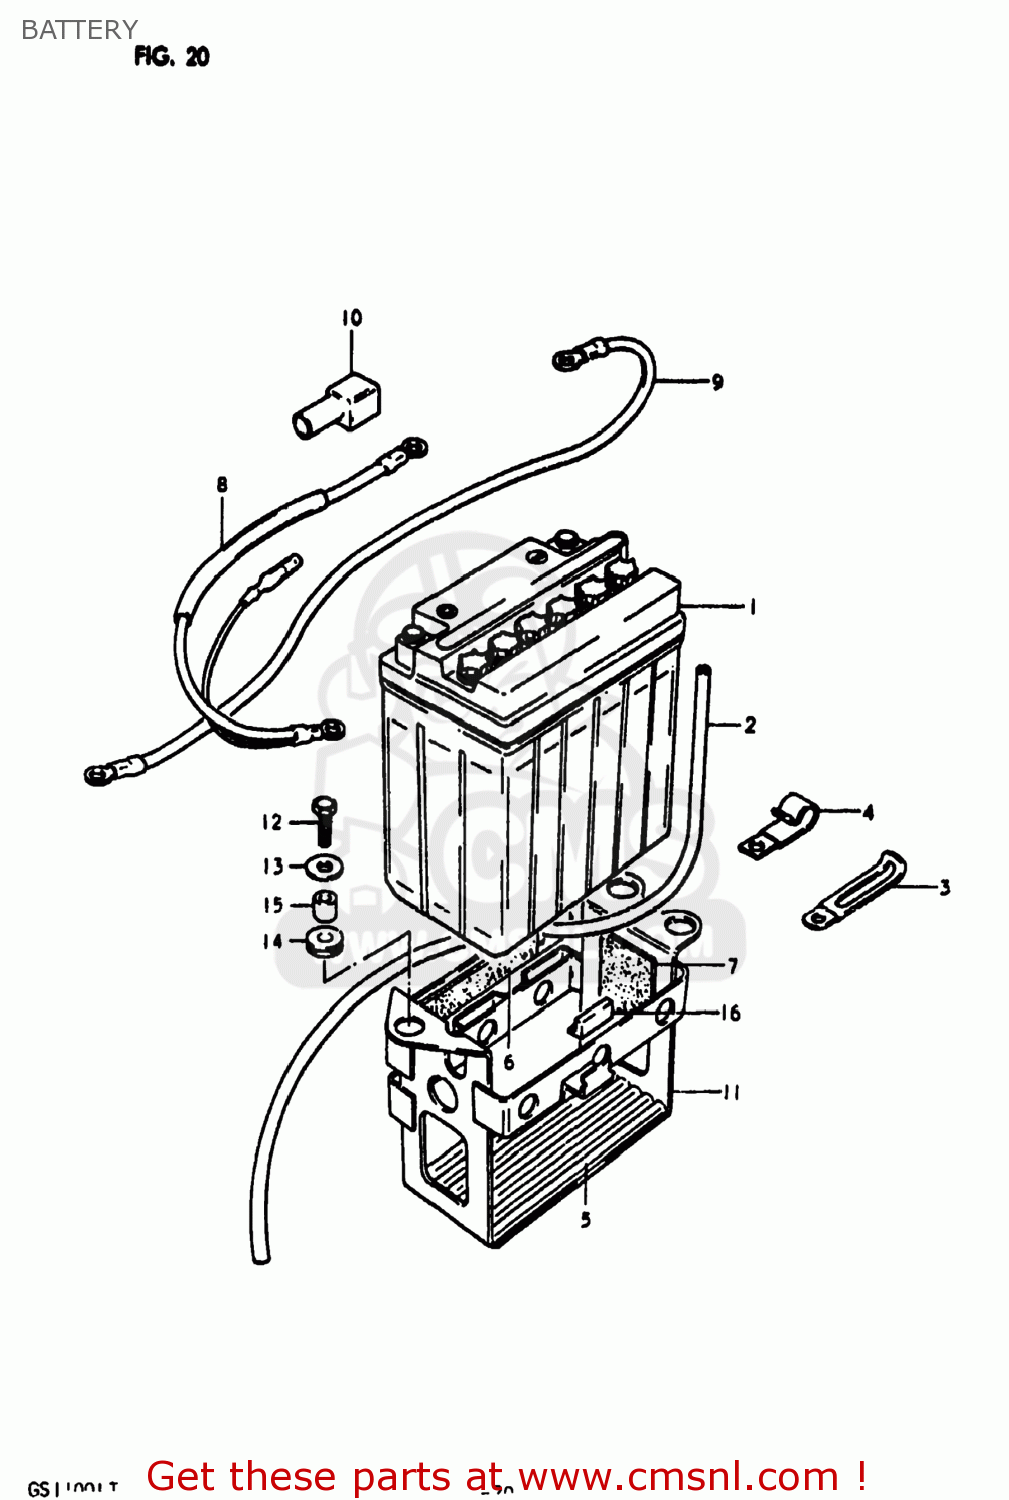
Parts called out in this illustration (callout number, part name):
1	BATTERY ASSY (12V)
2	HOSE,BATTERY EXHAUST
3	CLAMP L:35
4	CLAMP
5	PROTECTOR,BATTERY
6	PROTECTOR(20X90)X4
7	PROTECTOR,BATTERY
8	WIRE,BATTERY PLUS
9	LEAD WIRE,BATTERY(-)
10	CAP,TERMINAL
11	HOLDER,BATTERY
12	BOLT, UPPER
13	WASHER
14	CUSHION
15	SPACER(6.1X9X7.5)
16	CUSHION,FRAME COVER
